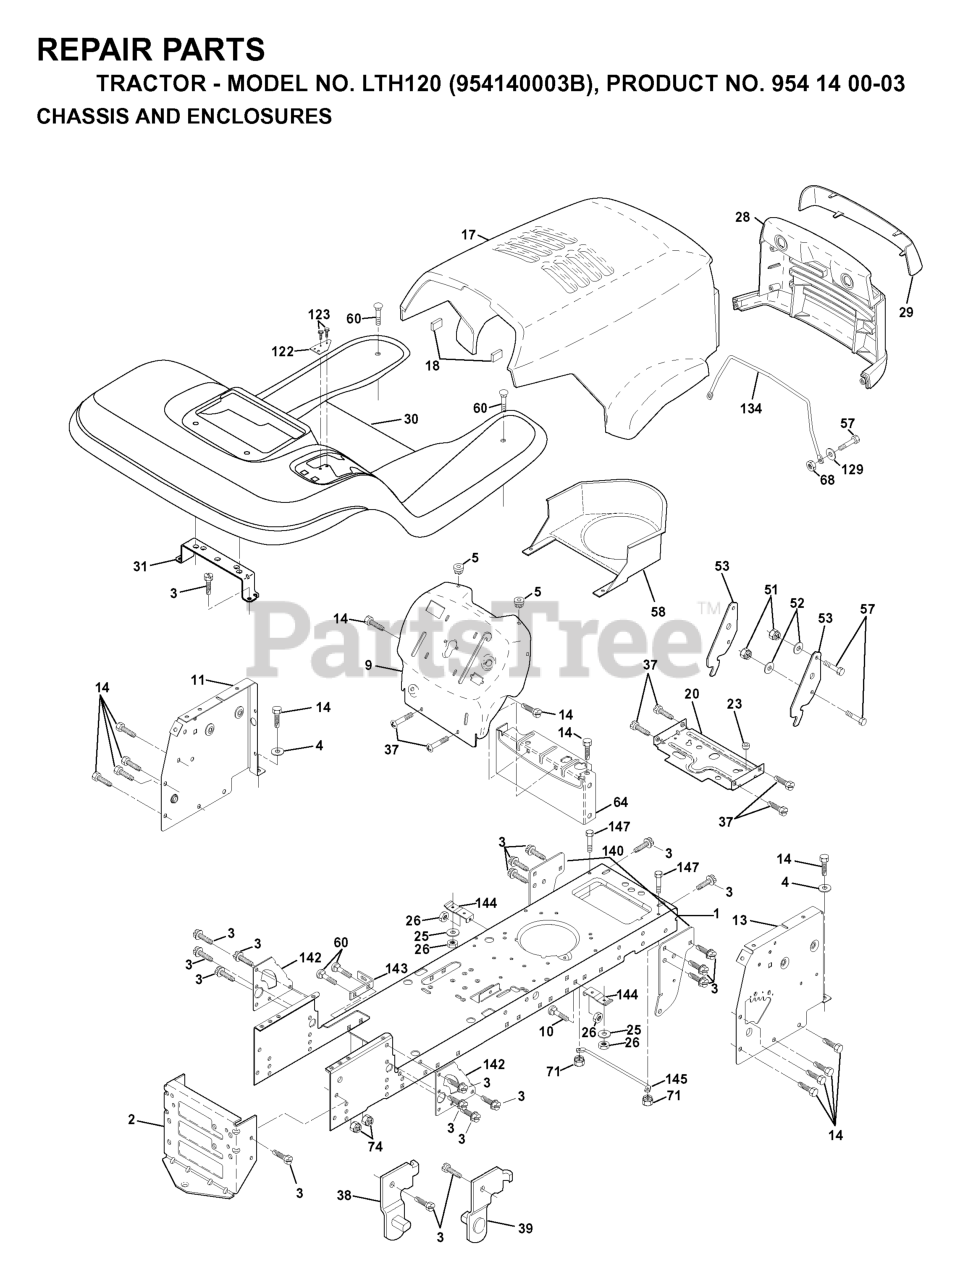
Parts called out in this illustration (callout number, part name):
1	CHASSIS WELDMENT
2	STRETCH DRAWBAR
3	SCREW
4	Washer 13/32 X 3/4 X 16 Ga.
5	BUMPER.RUBBER.HOOD
10	BOLT D
11	PANEL DASH LH
13	PANEL DASH RH
17	HOOD - LT/YT
18	BUMPER HOOD T
20	PLATE MTG
23	BUSHING.SNAP.NYL.BLK.
25	WASHER
26	NUT
28	GRILLE LT/PL HUSQVARNA
29	LENS LT/PL HUSQVARNA
30	FENDER FOOTREST
31	BRACKET.SUPPORT.FENDER
37	Screw 5/16-18 x 1/2 Hex, Self Tapping 5/16-18 x 1/2
38	BRACKET LH PIVOT
39	BRACKET RH PIVOT
51	LOCKNUT.NYLOC.1/4-20
53	BRACKET PNT PICK OFF LT/PL
57	BOLT
58	AIR DUCT P/L/LT
60	Bolt - Rd. Hd. Sq. Neckiage 3/8 16 x 3/4
64	DASH LOWER
68	NUT
71	NUT.CROWNLOCK.1/4
122	BRACKET SHIFT STLT
123	SCREW.TT.#10-32X.5.3/8.FLANGE
134	ROD SUPPORT HOOD LT/PL HUS.
140	BRACKET SUSPENSION FRONT
142	PLATE REINFORCEMENT
143	BRACKET, SWAY BAR
144	BRACKET FOOTREST
145	ROD PIVOT CHASSIS/HOOD
147	BOLT.HEX.1/4.X.3/4.DICHROMATE
